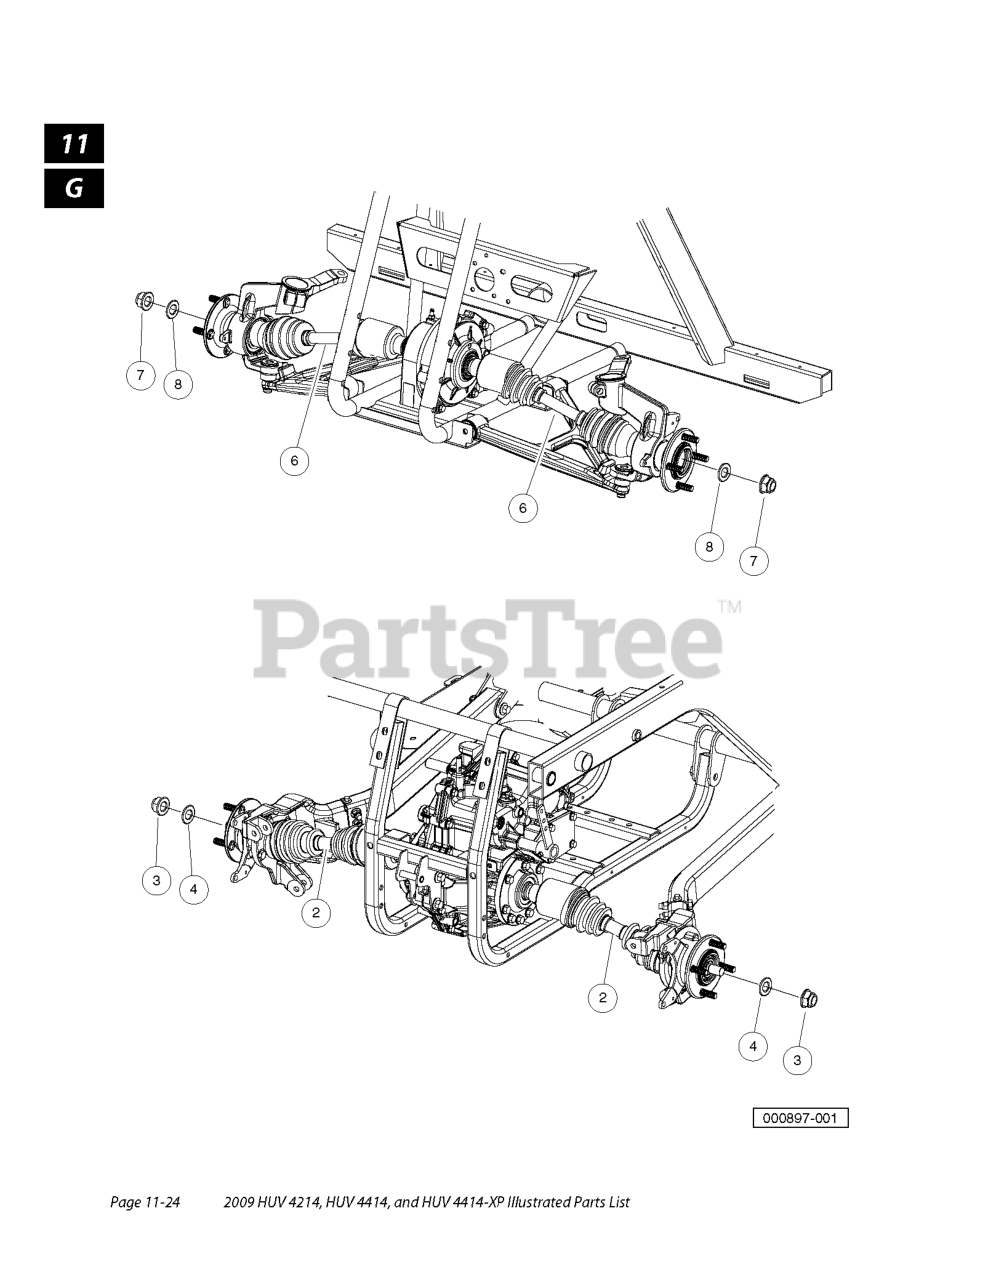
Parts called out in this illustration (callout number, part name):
3	NUT, STAKE, M18, HALFSHAFT
4	WASHER, FLAT, M18
6	HALFSHAFT, FRONT, 4X4
7	NUT, STAKE, M18, HALFSHAFT
8	WASHER, FLAT, M18
